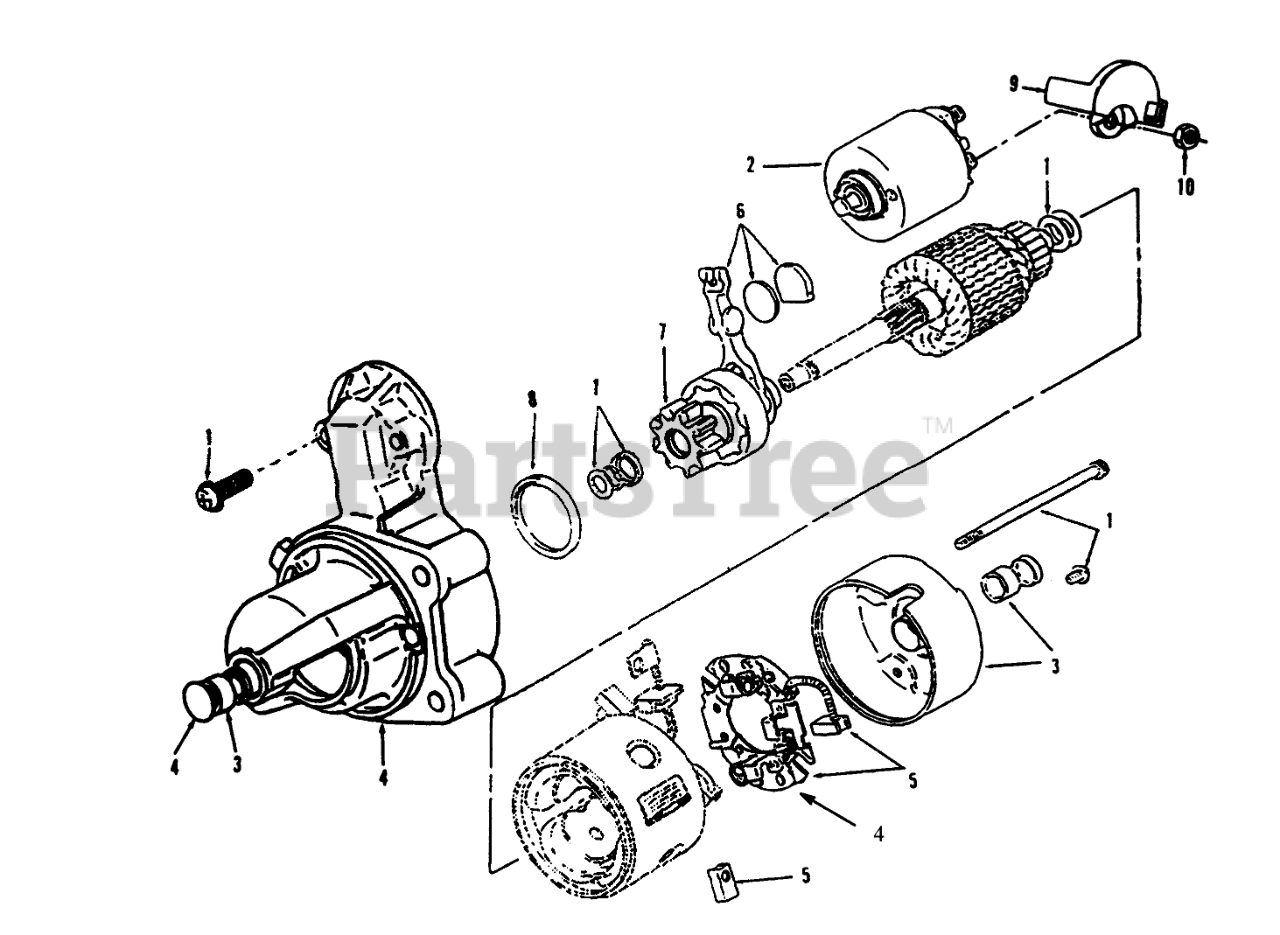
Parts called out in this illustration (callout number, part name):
1	Kit-Hardware, Starter (Includes (2) Solenoid Mtg Screws, 2 Thru Bolts, Armature Shims, Pinion Collar, & Retaining Ring)
2	Kit-Solenoid, Starter (Includes Solenoid & Spring Plunger)
3	Kit-Bushing, Starter (Includes Rear Cap with Bushing & Front Bushing)
4	Kit-Mounting Bracket (Incl. Ref.#5)
5	Kit-Brush, Starter (Includes(2) Negative & (1) PositiveBrushes)
6	Kit-Shift Lever, Starter (Includes Lever, Wear Plate & Rubber Plug)
7	Clutch Assembly-Starter (Includes Pinion Gear)
8	Dust Seal
9	Cap-Starter Solenoid
10	Nut-M8
